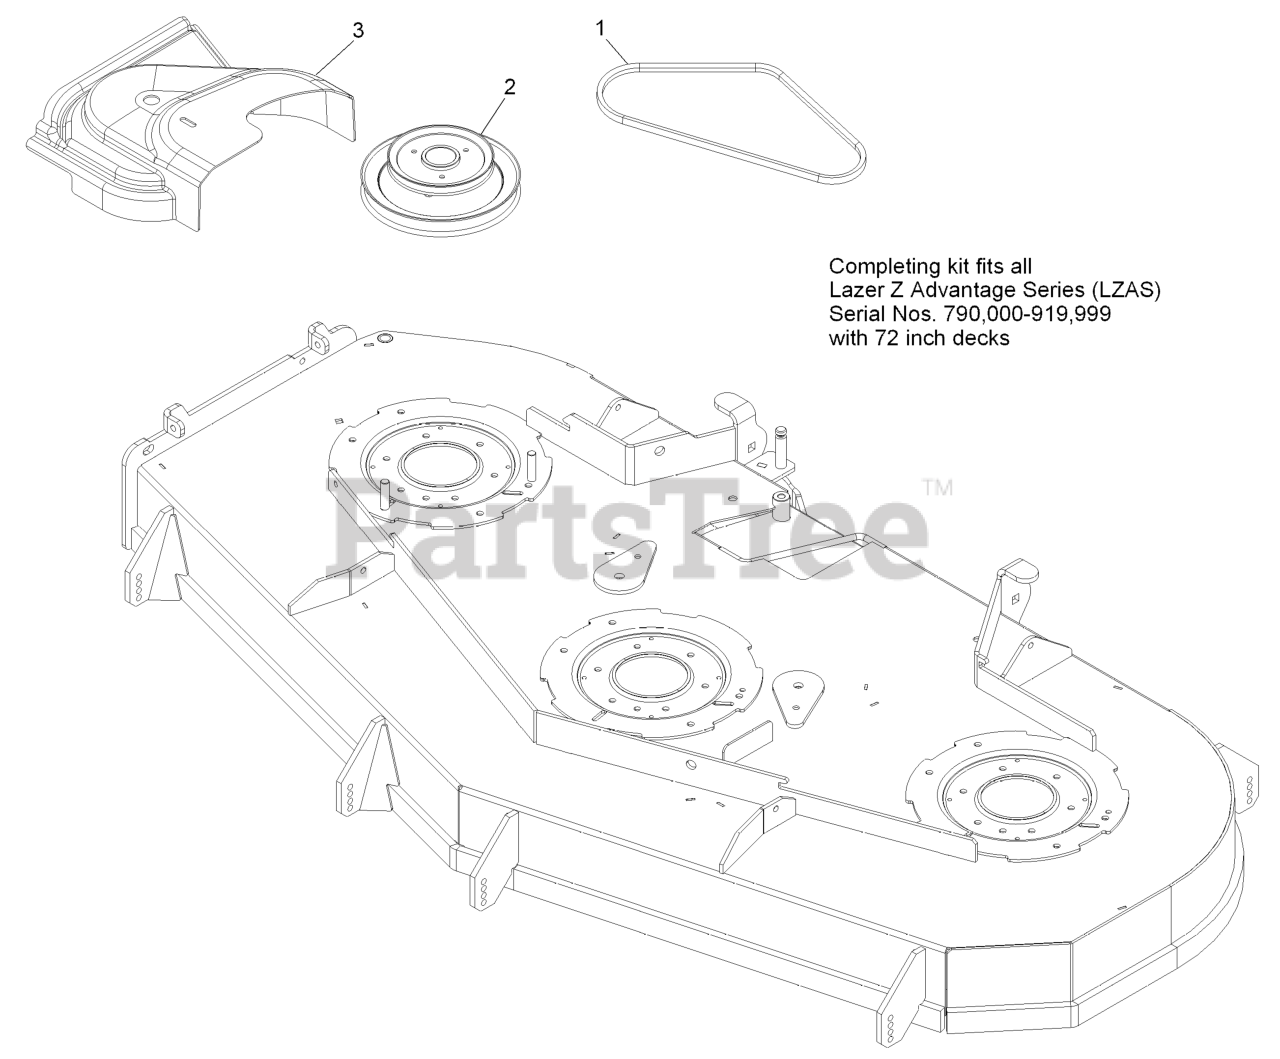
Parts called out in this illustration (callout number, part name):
1	BELT, BLOWER DRIVE 72
2	JACKSHAFT,UV DRIVE 724
3	COVER,BELT UV 72
